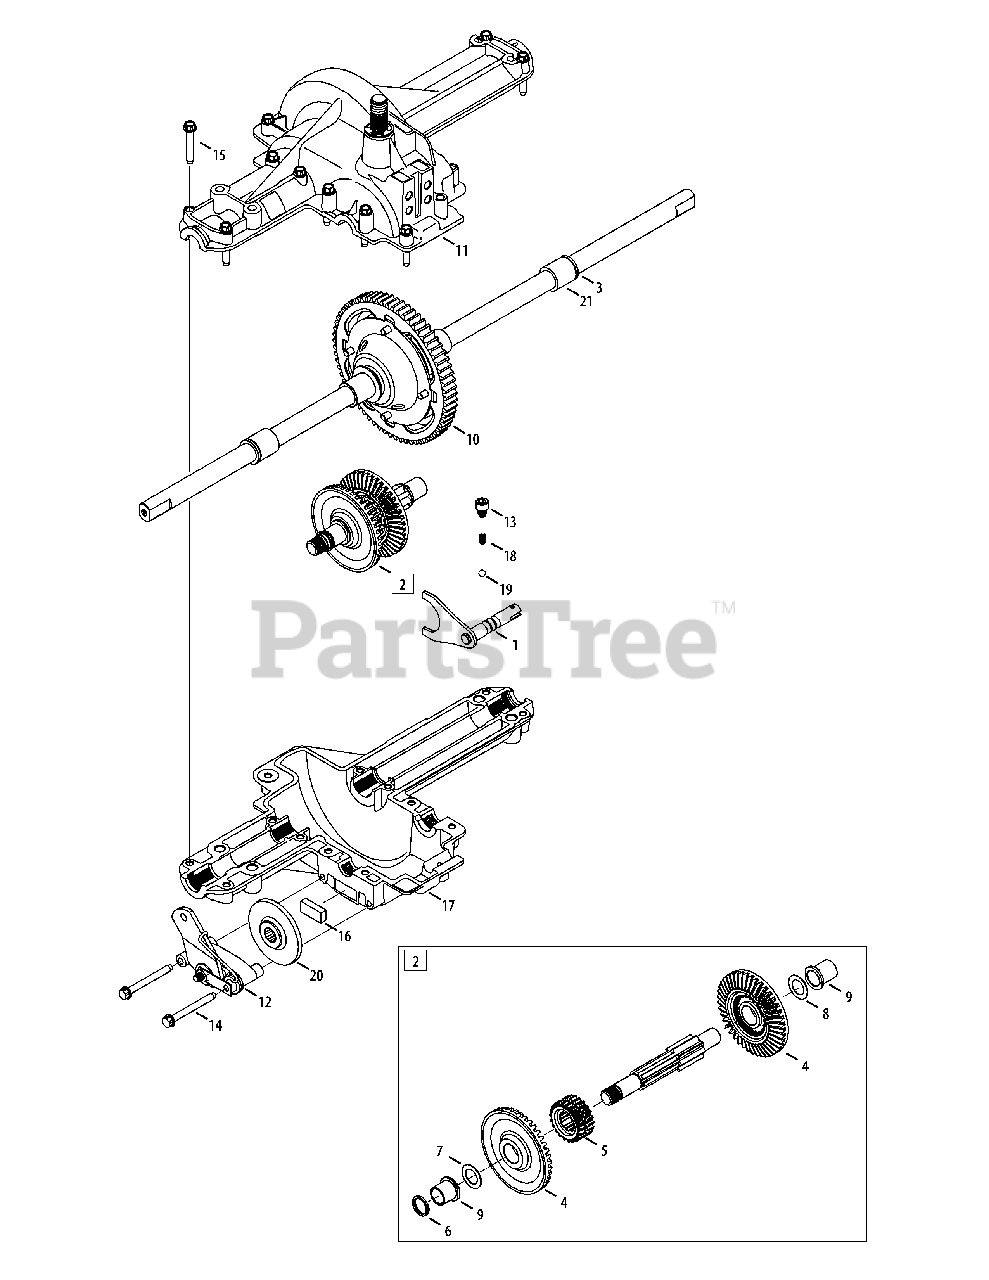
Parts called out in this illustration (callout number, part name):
1	Detent Shaft Ass’y
2	Drive Shaft
3	Oil Seal .750 x 1.00 x .125
4	Bevel Gear, 42 tooth spline
5	Single Speed Clutch Collar
6	Seal .625 x .812 x .094
7	Flat Washer 5/8 ID x 1.0 OD x .030
7	Flat Washer 5/8 ID x 1.0 OD x 0.040
7	Flat Washer 5/8 ID x 1.0 x .020
7	Thrust Wash. 5/8" ID x 1.0" OD x .035
7	Thrust Wash. 5/8" ID x 1.0" OD x .025
8	Flange Bearing 5/8 x 3/4
9	Flange Bearing 5/8 x 15/16
10	Differential Assembly
11	Upper Housing
12	Brake Assembly
13	Self-Tap Scr. 5/16-18 x .375
14	Self-Tap Scr. 1/4-20 x 2.375
15	Self-Tap Scr. 1/4-20 x 1.625
17	Lower Housing
18	Compression Spring
19	Ball Detent .250 Dia.
21	Sleeve Bearing 3/4 ID x 1.0
